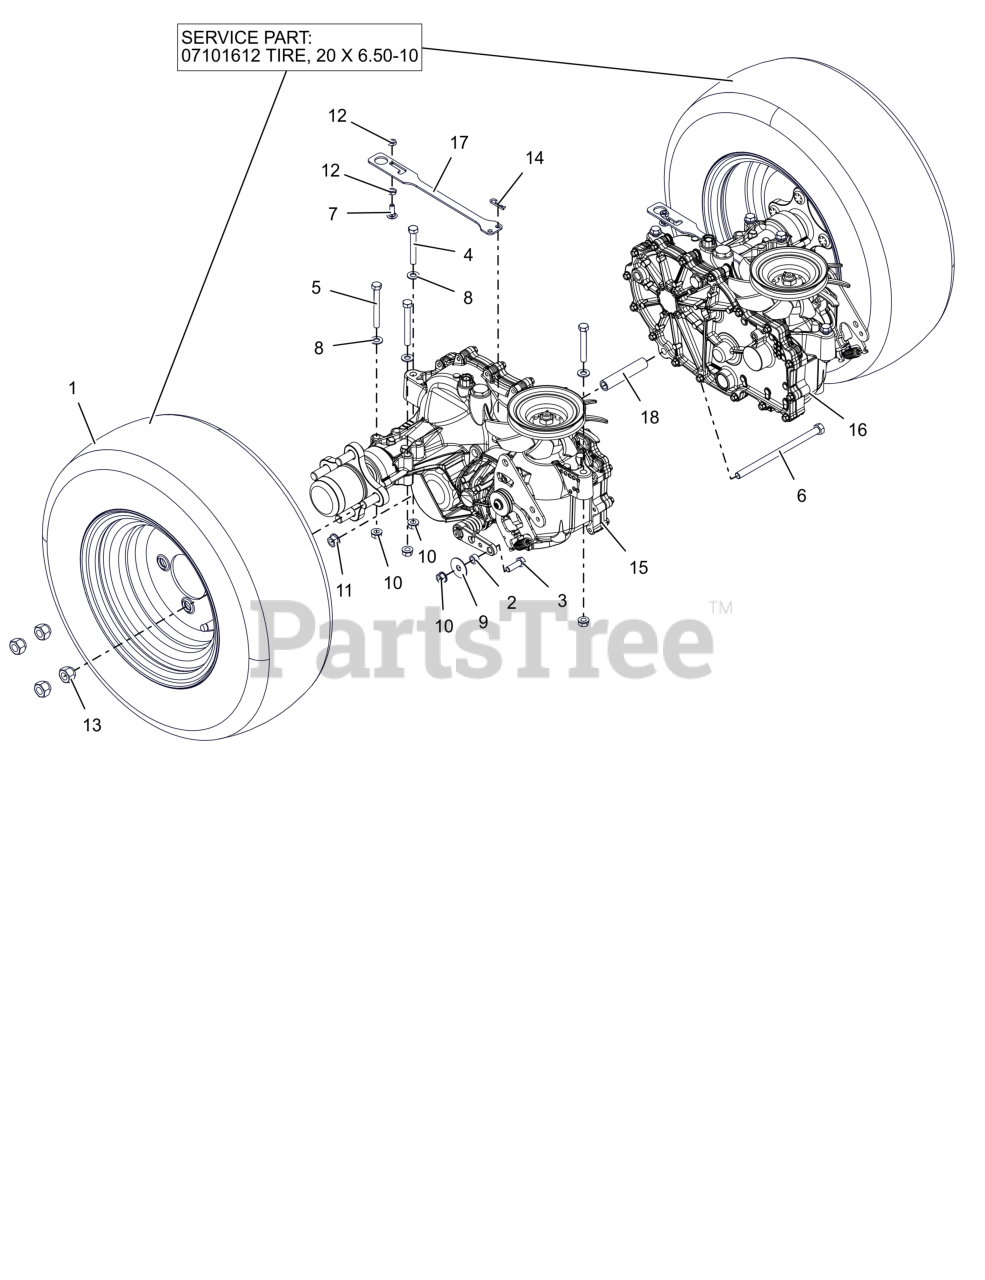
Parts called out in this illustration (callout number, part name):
1	ASM- WHL/TIRE 20X6.50-
1	TIRE, 20 X 6.50-10
2	SPCR- SLV .344 X .500 X .283
3	BLT,HEX .31-18X1.00 G5 ZCC
4	BLT, HEX .31-18X2.25 G5 ZCC
5	BLT, HEX .31-18X2.75 G5 ZCC
6	BLT, HEX .38-16X6.50 G5 ZCC
7	BLT, RHSN .25-20X.750 G5 ZCC
8	WSHR,FLT .344X.688X.065 ZCC
9	WSHR, FLT .347X1.254X.048 ZCC
10	NUT,LK-CTR-FLG .31-18 GF ZCC
11	NUT-LK-CTR-FLG .375-16 GF ZCC
12	NUT-LK-CTR-JAM .250-20 GB ZCC
13	NUT, WHEEL .50-20 ZCC
14	PIN, HAIR #213 .08X1.19 ZCC
15	TRANSAXLE- HG 32" RH
16	TRANSAXLE- HG 32" LH
17	LEVER-TRANSAXLE DMP VALVE(BLK)
18	SPCR- 32" TRANS
